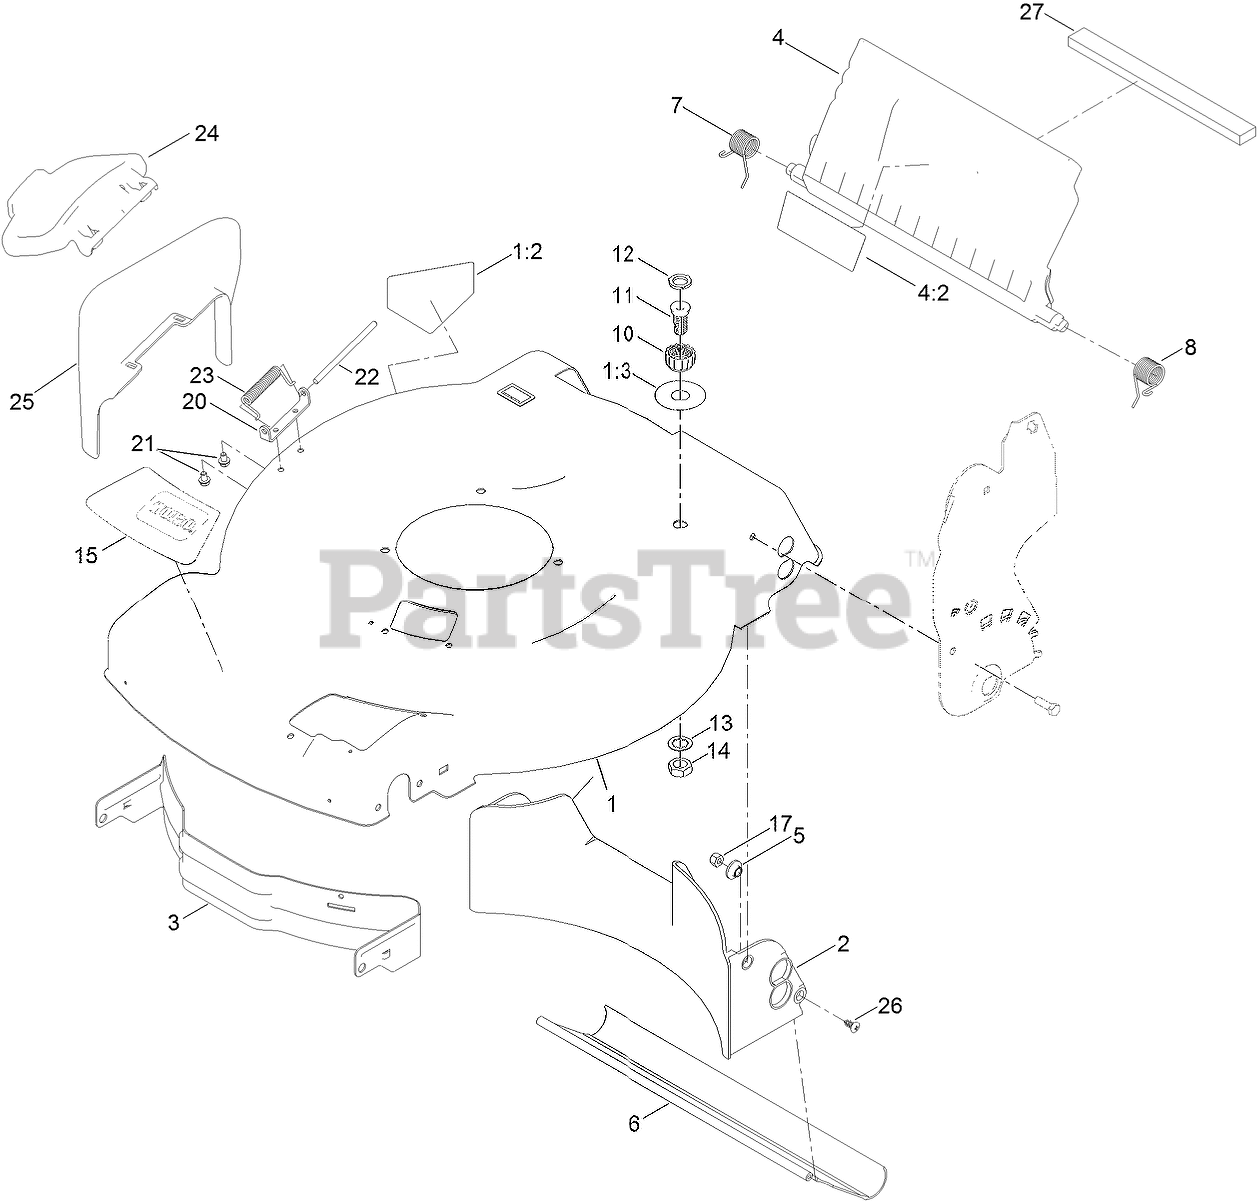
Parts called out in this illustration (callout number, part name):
1	HOUSING ASM
1:2	DECAL-DANGER
1:3	DECAL-QUICK WASH
2	BAFFLE-REAR
3	BAFFLE-FRONT
4	REAR DEFLECTOR ASM
4:2	DECAL-WARNING
5	WASHER-STEPPED, BAFFLE
6	SHIELD-TRAILING
7	SPRING-TORSION
8	SPRING-TORSION
10	COUPLING-HOSE, WASHOUT PORT
11	PORT-WASHOUT
12	WASHER-SEAL, WASHOUT PORT
13	WASHER-LOCK
14	NUT-JAM
15	DECAL-DECK, RECYCLER
17	NUT-LOCK, NI
20	BRACKET-COVER
21	SCREW-HWH
23	SPRING-TORSION
24	DEFLECTOR-SIDE
25	CHUTE-DISCHARGE, SIDE
26	SCREW-PTH
27	FOAM-SEAL
